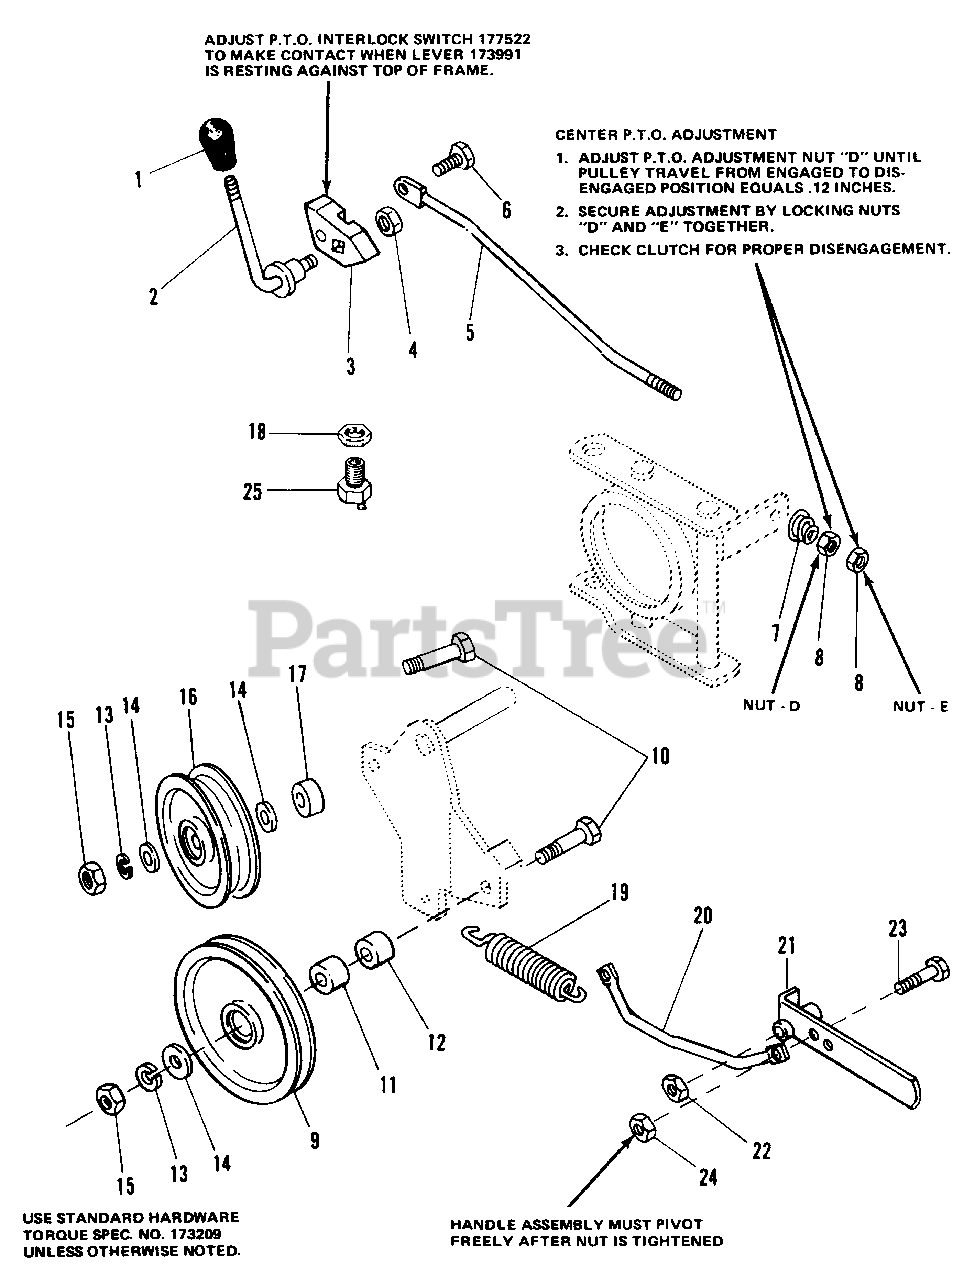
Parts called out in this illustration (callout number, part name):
1	KNOB
2	HANDLE, CIutch P.T.O.
4	LOCKNUT, Hex, 3/8-16
5	CONTROL ROD ASSEMBLY
6	CAPSCREW, Special
8	NUT, Hex, Full, 5/16-18
10	CAPSCREW, Hex Hd., 3/8-16 x 2
13	LOCKWASHER, 3/8
14	WASHER, 5/16
15	NUT, Hex, Full, 3/8-16
18	NUT, Pal
19	SPRING, Tension
20	ROD, Tension
21	HANDLE ASSEMBLY
22	LOCKNUT, Hex, 7/16-14
23	CAPSCREW, Hex Hd., 5/16-18 x 3/4
24	LOCKNUT, Hex, 5/16-18
25	SWITCH, Interlock
